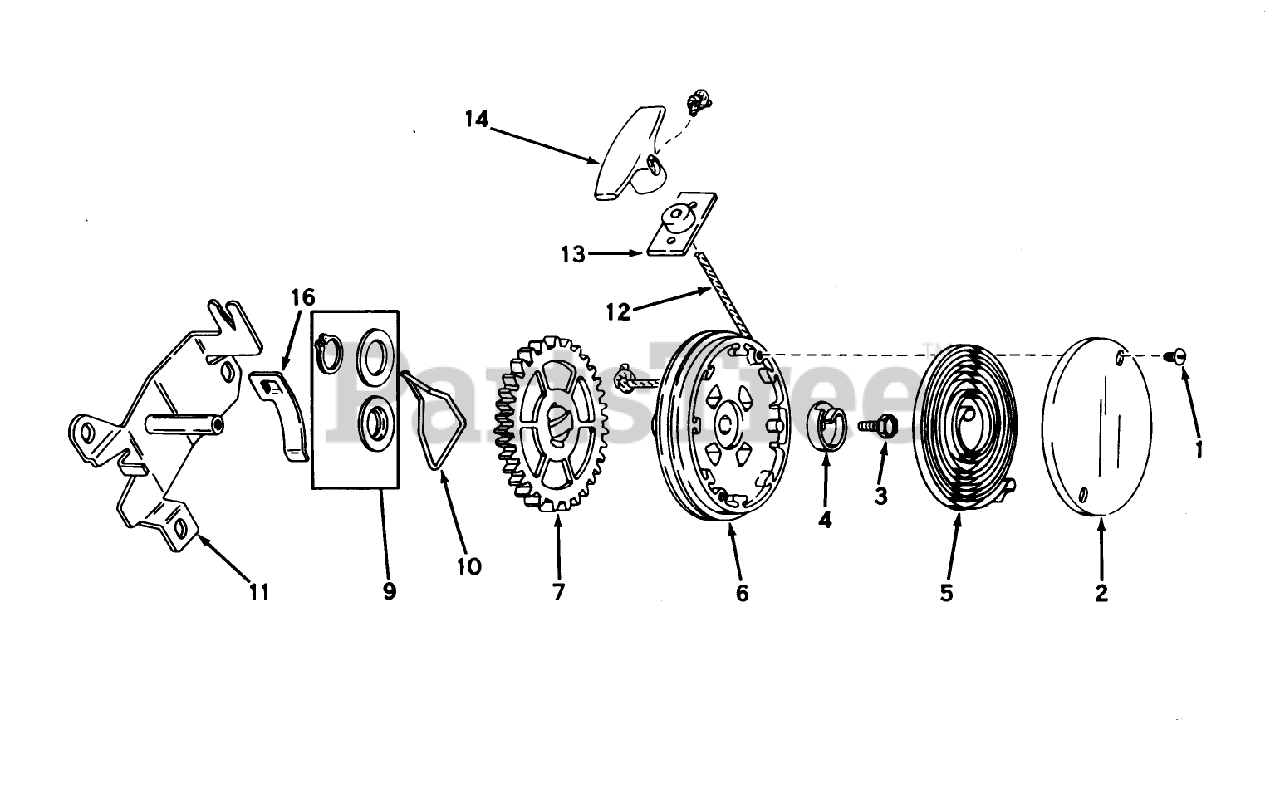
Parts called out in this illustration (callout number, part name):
2	Cover, Spring
3	Screw, Hex Washer Head
4	Hub Spring
5	Spring, Rewind
6	Pulley Assy. (Incl. Ref. #9)
9	Kit, Thrust Wash. & Snap Rg.
11	Bracket Assy. Mounting
12	Rope-Starter
13	Bracket Assy.
14	Handle-Starter
16	Clip Rope
